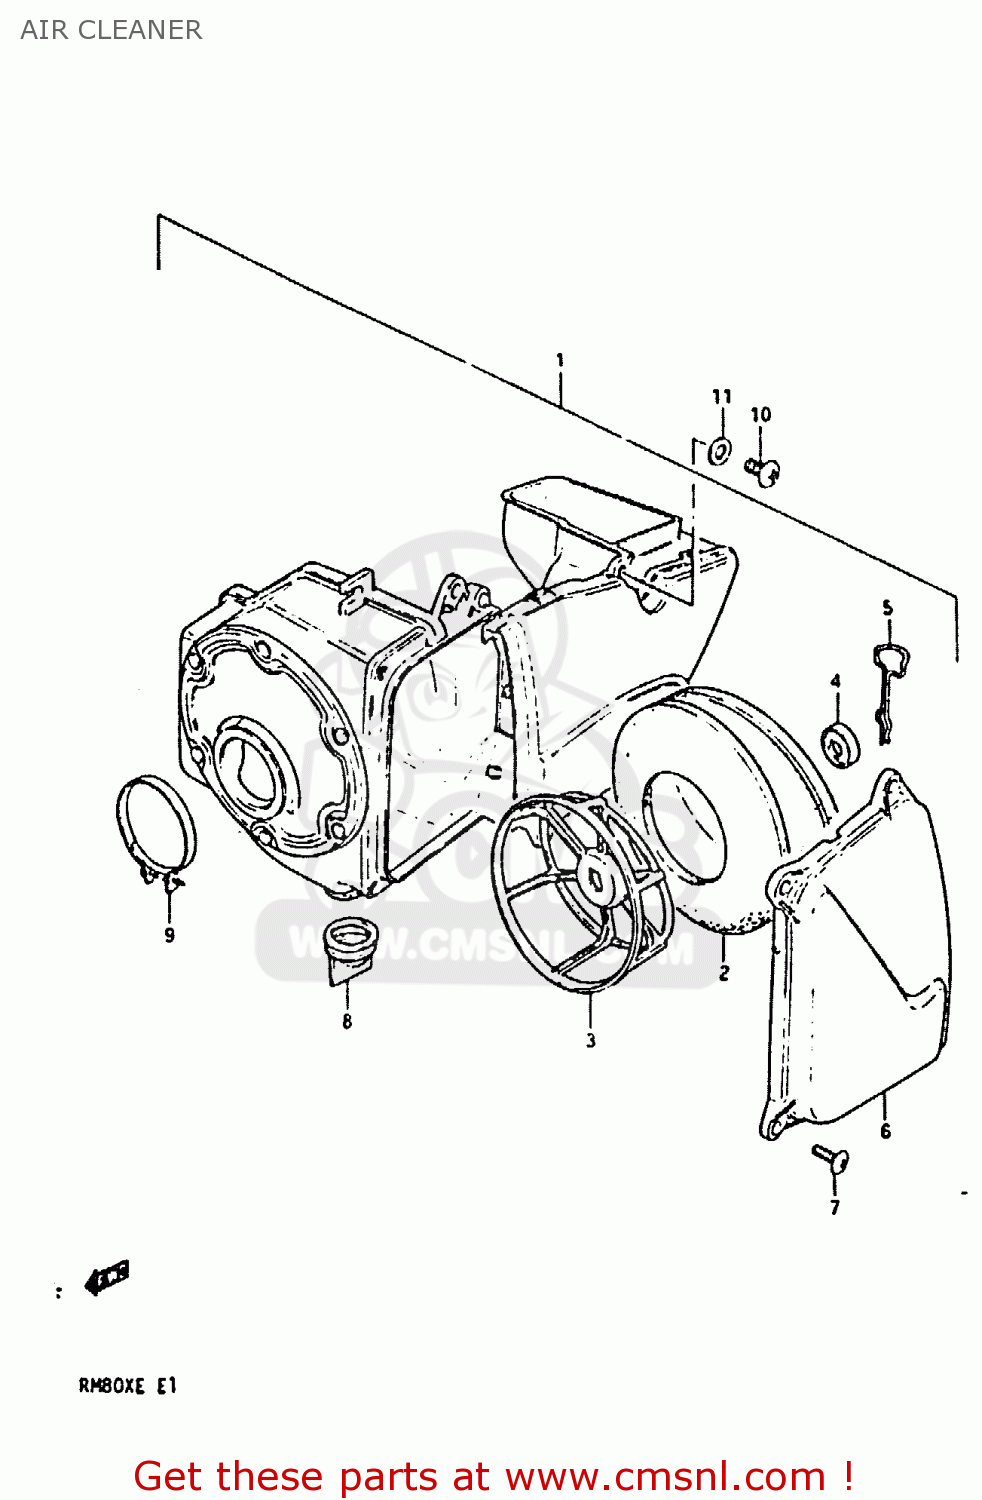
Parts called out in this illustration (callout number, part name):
1	CLEANER ASSEMBLY,AIR
2	FILTER,AIR CLEANER
3	HOLDER,AIR CLEANER
4	WASHER
5	PIN,SNAP
6	CAP,AIR CLEANER
7	SCREW M5X12 DIN 7985/N
8	HOSE,AIR CLEANER DRAIN
9	CLAMP
10	SCREW
11	WASHER
